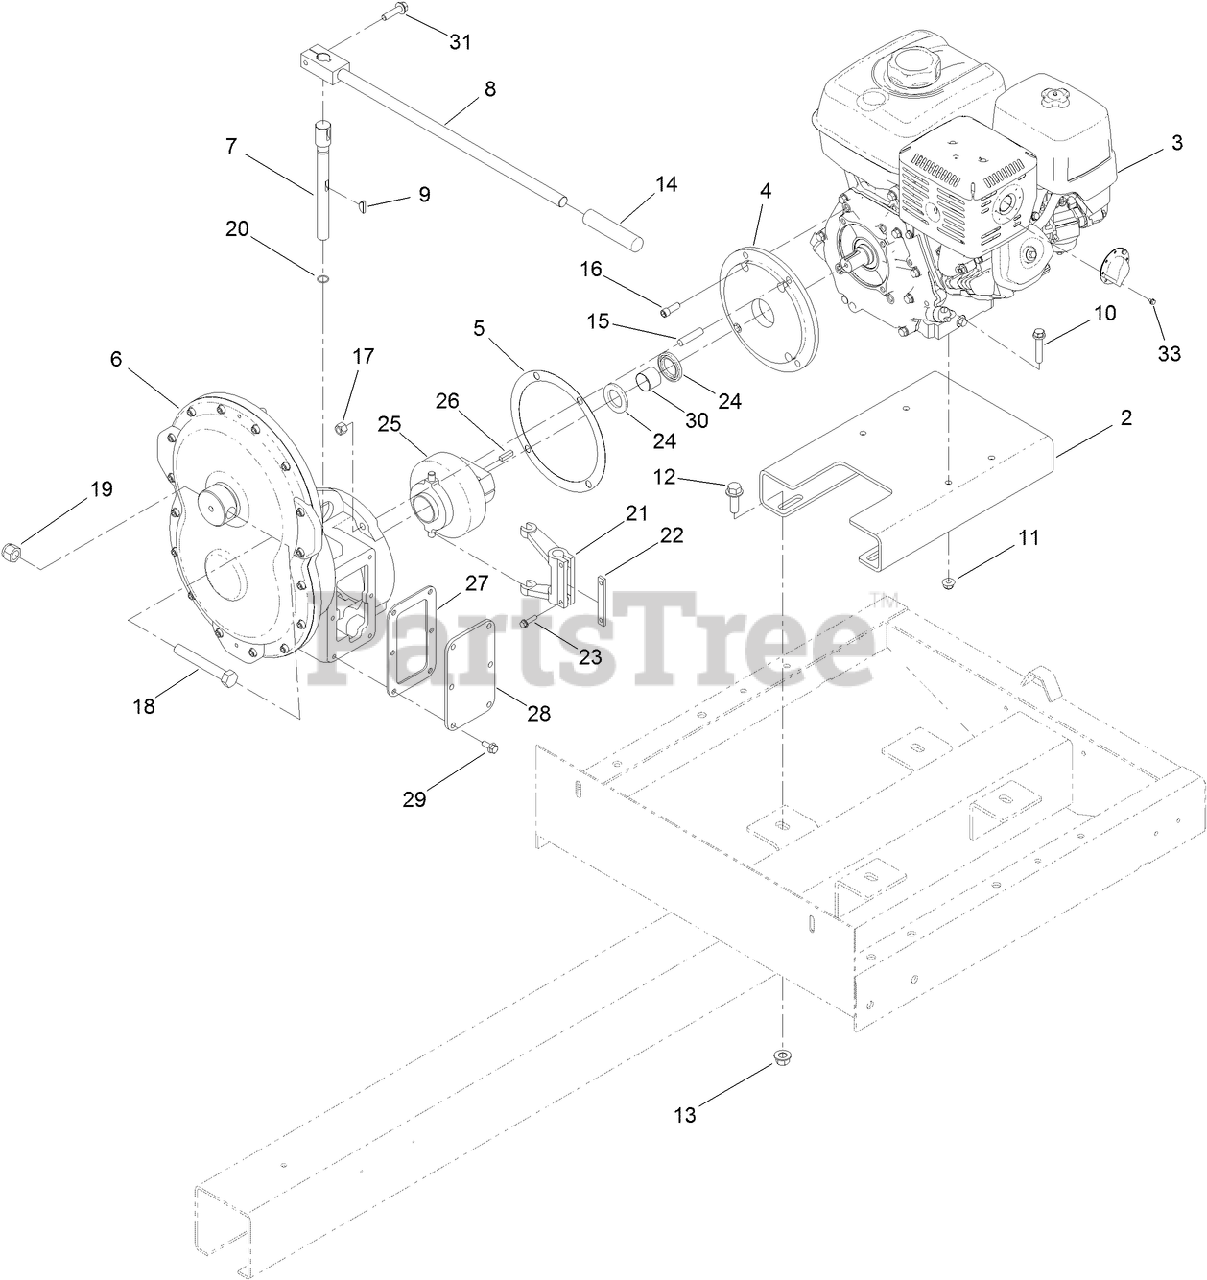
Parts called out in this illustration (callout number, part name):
2	BASE-MOTOR
3	ENGINE-HONDA, GX340
4	ADAPTOR-ENGINE
5	GASKET-ADAPTER, ENGINE
7	SHAFT-CLUTCH
8	HANDLE-CLUTCH
9	KEY-WOODRUFF
10	SCREW-HHF
11	NUT-HF, NI
12	SCREW-HHF
13	NUT-LOCK
14	GRIP-FLEX
16	SCREW-HSH
17	NUT-LOCK, NI
18	SCREW-HH
19	NUT-LOCK, NI
20	O-RING
21	FORK-CLUTCH
22	SPACER-FORK, CLUTCH
23	SCREW-HHF
24	SEAL-SHAFT
25	CLUTCH-DISCONNECT, SLIP
27	GASKET-ACCESS, CLUTCH
28	COVER-ACCESS, CLUTCH
29	SCREW-HHF
30	BUSHING-SHAFT
31	SCREW-HHF
33	SCREW-HWH
